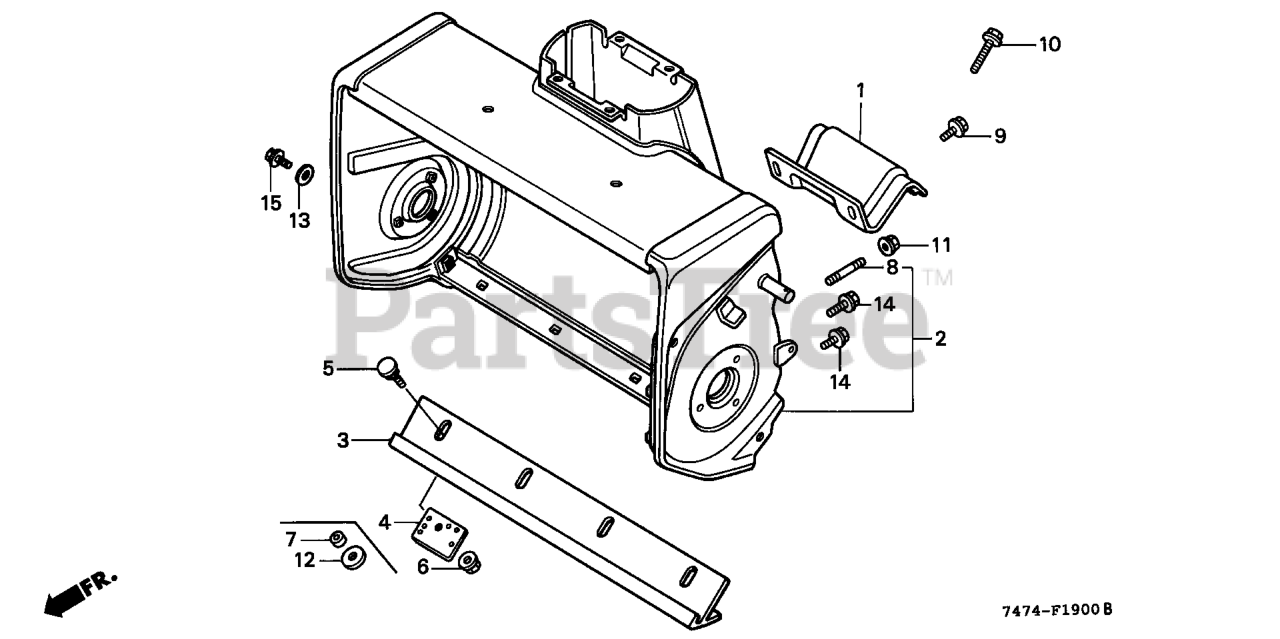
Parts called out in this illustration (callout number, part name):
1	STIFFENER, FRAME
2	HOUSING, AUGER *NH1* (BLACK)
3	BLADE, SCRAPER
4	PLATE, SCRAPER HOLDER
5	BOLT, PAN (6MM)
6	NUT, SELF-LOCK (6MM)
8	BOLT 2, STUD (6X18)
9	BOLT-WASHER (6X16)
10	BOLT-WASHER (6X28)
11	NUT, FLANGE (6MM)
13	WASHER, PLAIN (6MM)
14	BOLT, FLANGE (6X12) Use up to Engine SN 1543277.
15	BOLT, FLANGE (6X12)
